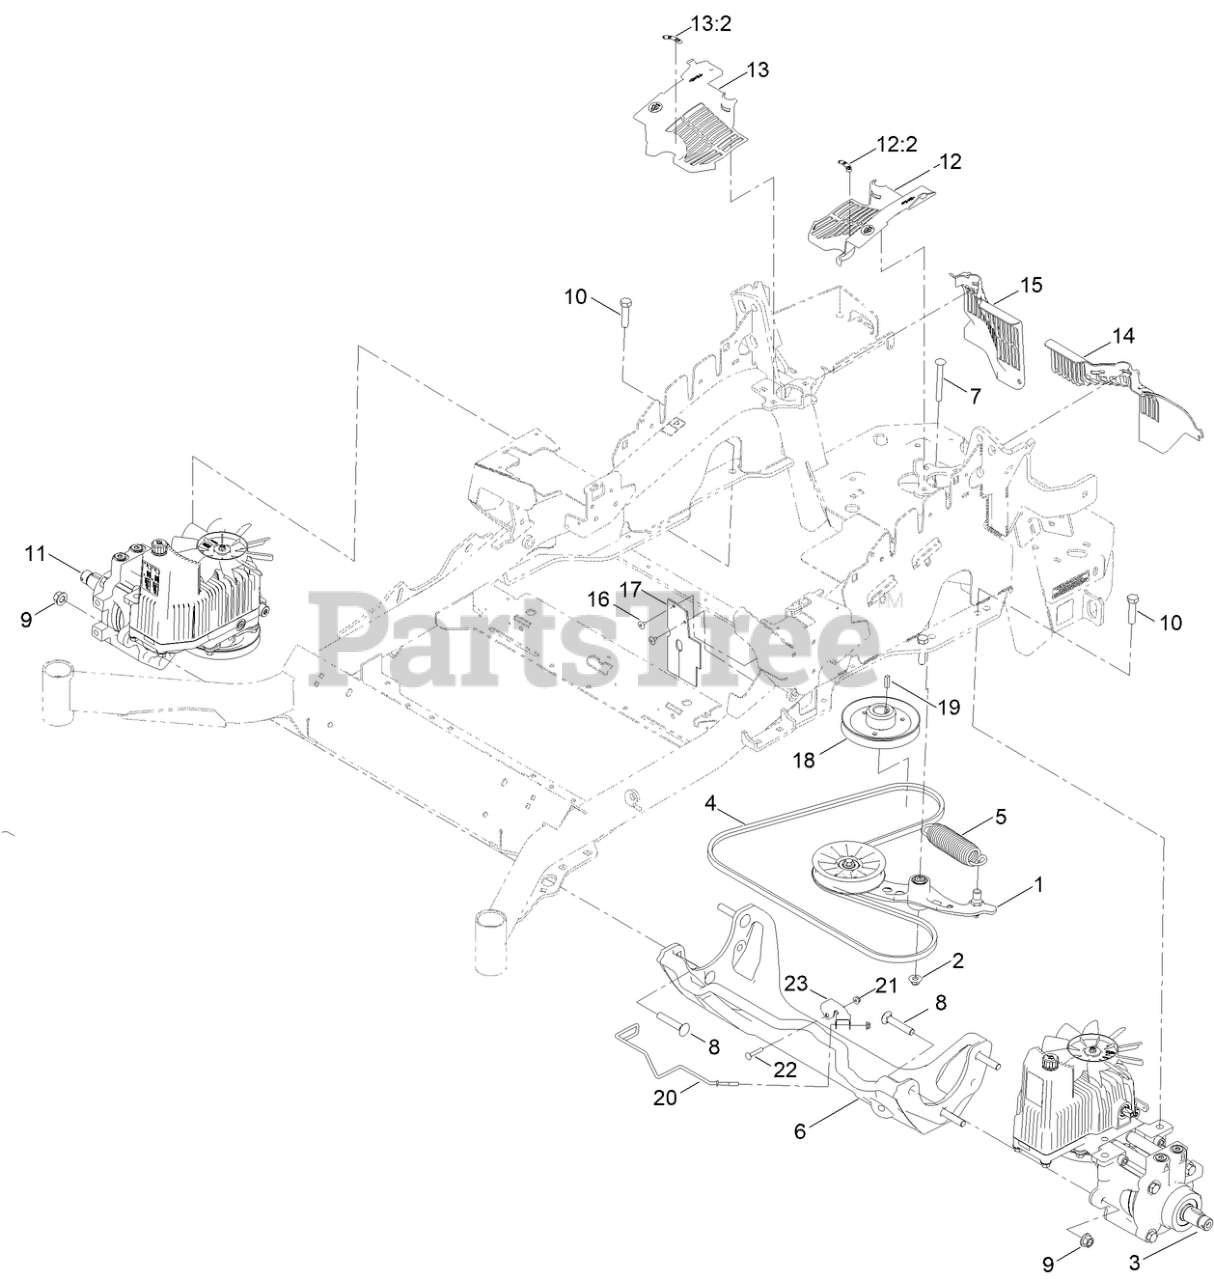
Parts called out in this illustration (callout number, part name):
1	PUMP IDLER ASM
2	NUT-FLANGE, NI
3	HYDRO-LH
4	BELT-V
5	SPRING-EXTENSION
6	CRADLE-HYDRO
7	BOLT-SHOULDER, CARRIAGE
8	SCREW-CARR
9	NUT-LOCK
10	SCREW-HH
11	HYDRO-RH
12	LH HYDRO GUARD ASM
12:2	DECAL-OIL, HYDRO
13	RH HYDRO GUARD ASM
13:2	DECAL-OIL, HYDRO
14	GUARD-HYDRO REAR, LH TRIM
15	GUARD-HYDRO, REAR (RH)
16	RIVET-POP
17	DEFLECTOR-AIR FLOW
18	SHEAVE, W/HUB
20	GUIDE-BELT
21	NUT-HF
22	SCREW-CARR
23	BRACKET-U
